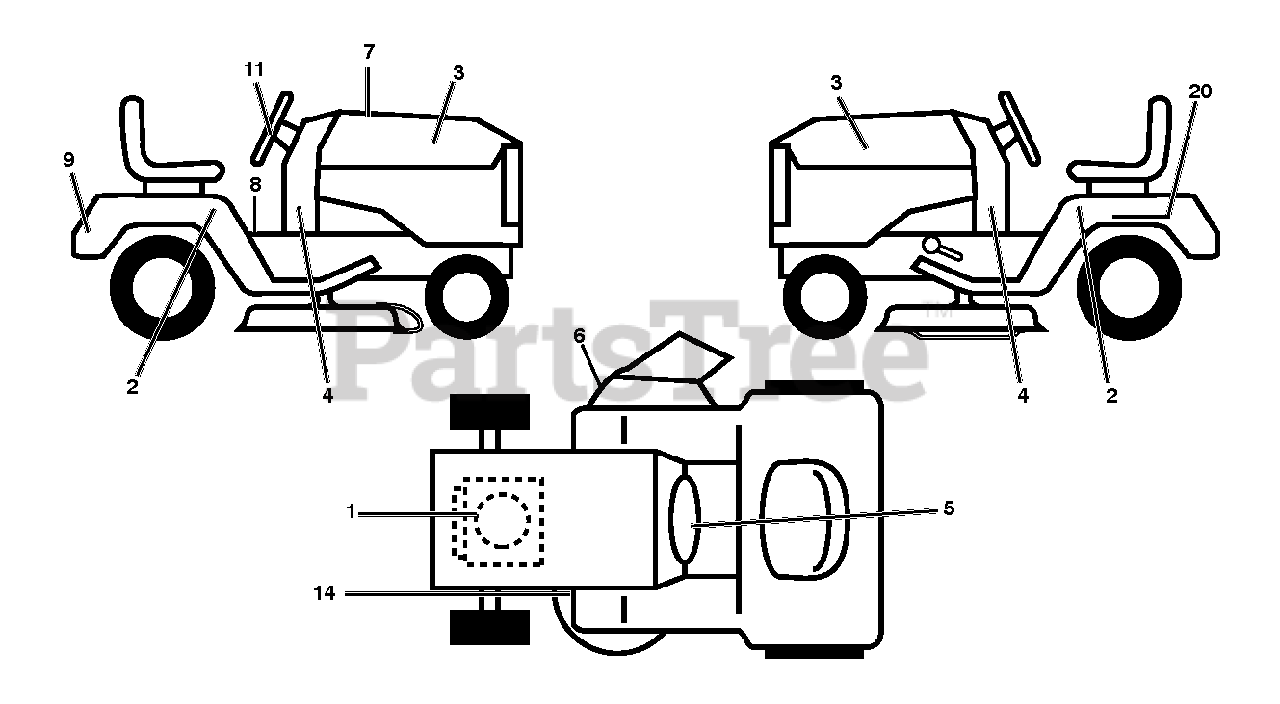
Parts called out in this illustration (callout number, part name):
2	DECAL.FEND.RH/LH.SET.6S.POULAN
3	DECAL.HOOD.ALPHA.RH/LH.POULAN
6	DECAL.WARN.DFLECT/CTFINGR.SRD
8	Fender Engine Warning Decal
9	DECAL.FEND.POULAN.2010
11	DECAL.WHEEL.STRG.STDHRS.POULAN
20	DECAL BTRY SYMBOLS
